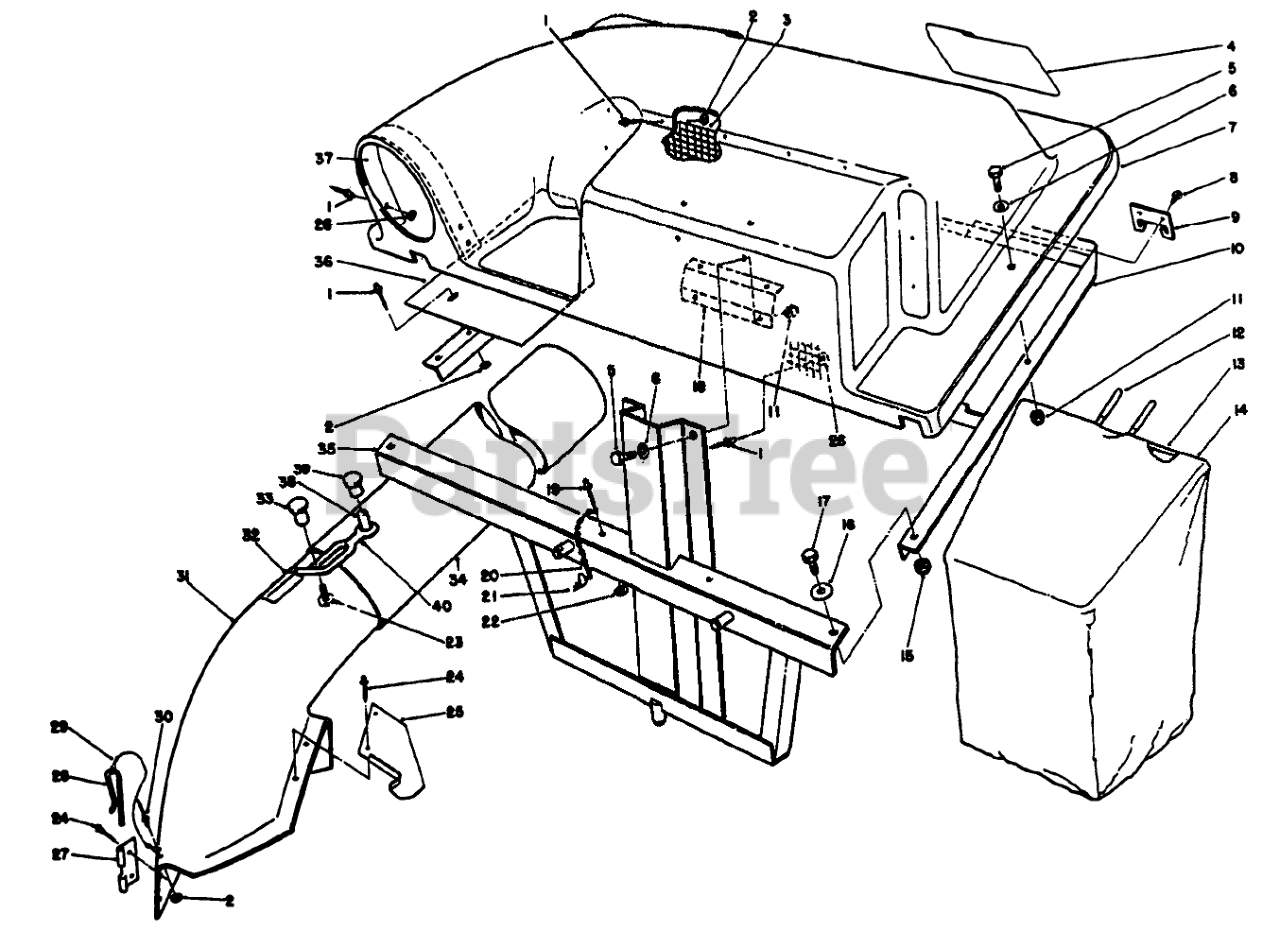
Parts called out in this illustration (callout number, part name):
1	RIVET-POP
2	WASHER-PLAIN
3	SCREEN
4	DECAL-BAGGER, TWIN
5	SCREW-HH
6	WASHER-PLAIN
7	COVER-BAGGER, TWIN
8	SCREW-HWH
9	BRACKET-FRAME, BAG
10	Cover-Frame
11	NUT-LOCK, NI
12	GRIP-HANDLE, BAG
13	Frame-Bag
15	NUT-LOCK, NI
16	WASHER-FLAT
17	SCREW-HH
18	Plate-Backup
20	10 LINK CHAIN W/O HOOK
21	PIN-HAIR
22	WASHER-BACK
23	Screw
24	RIVET-BLIND
25	CHUTE SUPT BRKT
26	WASHER-FLAT
27	BRACKET-MOUNTING, CHUTE
28	PIN-LOCKING, CHUTE
29	LANYARD
30	RIVET-BLIND
31	Assembly-Chute (Incl. Ref. #24-30 & 32)
32	DECAL-DANGER
34	TUBE(ROUND&LONG)
35	Frame-Mounting
36	Baffle
37	Support Inlet
38	SPACER-INTERLOCK
39	FASTENER-PANEL
40	RETAINER-DUCT
